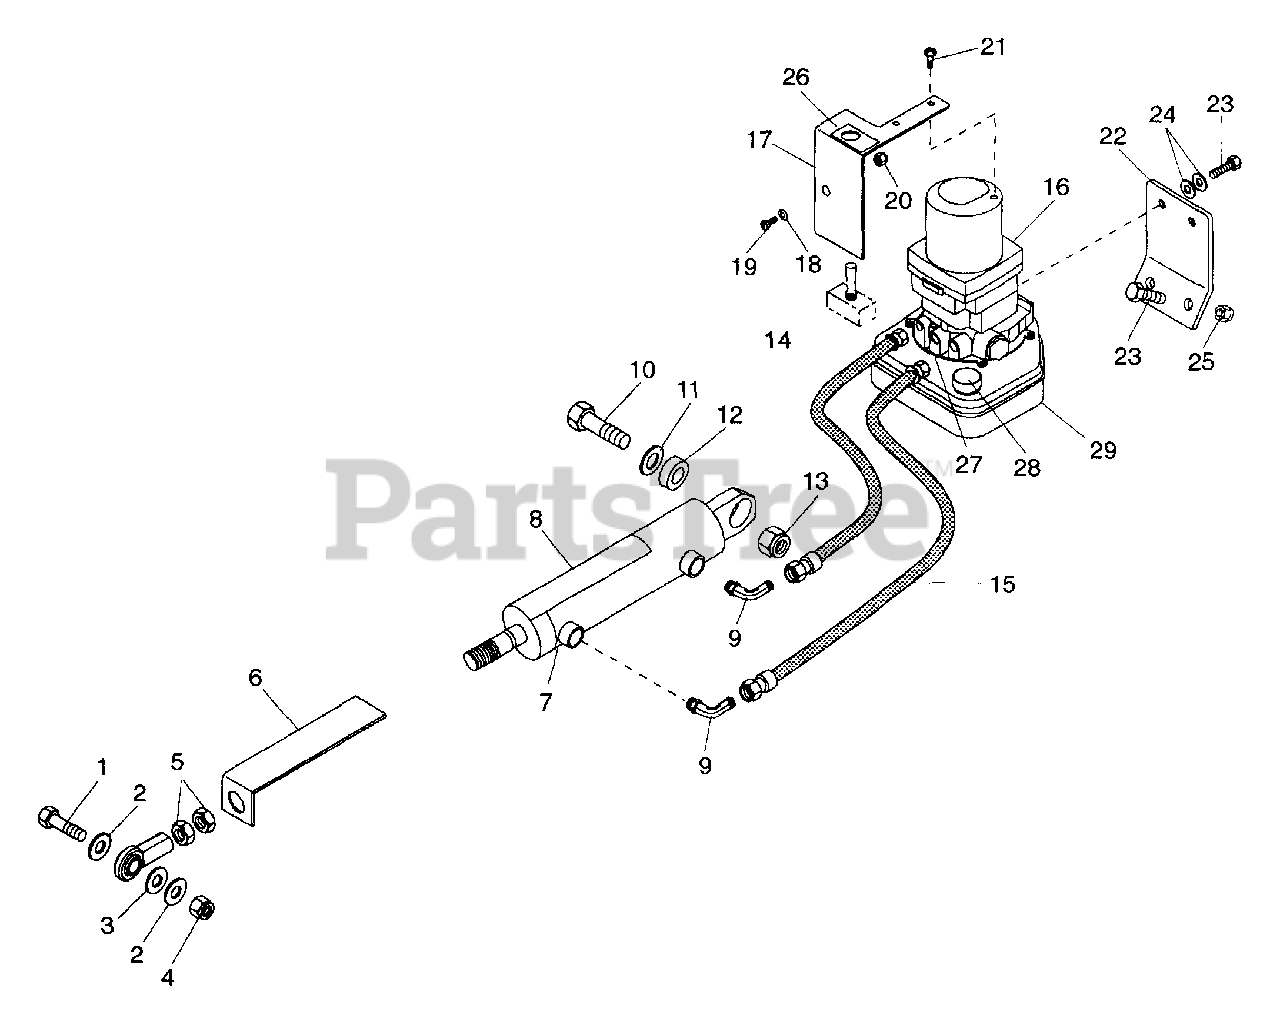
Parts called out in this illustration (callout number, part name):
1	Bolt-Hex .50-13 x 1.25 Grade 2
2	Washer-Flat-Steel .625 x 1.375 x .109
3	Rod End, 5/8" Female
4	Nut-Locking-Nylon .625-11 Grade 2
5	Nut-Jam .625-18
6	Strap-Height of Cut Indicator
7	Cylinder, Hydraulic Lift
8	Decal-Height of Cut
9	Adapter 2503-4-4
10	Bolt-Hex .50-13 x 2.25 Grade 5
11	Washer-Flat-Steel .531 x 1.250 x .100
12	Bushing, .516 x 1.000 x 1.050
13	Nut-Locking-Nylon .50-13 Grade 2
14	Assembly, Hose Pump to Cylinder
15	Assembly, Hose Pump to Cylinder
16	Pump, Electric Hydraulic
17	Switch Plate, Lift Pump
18	Washer-Flat-Steel .281 x .625 x .065
19	Screw-Machine .25-20
20	Nut-Locking-Nylon .250-20 Grade 2
21	Screw-Tapping 12-14 x .50
22	Lift Pump Mounting Bracket
23	Bolt-Hex .38-16 x .75 Grade 5
24	Washer-Flat-Steel .406 x .812 x .065
25	Nut-Locking-Nylon .375-16 Grade 2
26	Decal, Cutting Heat Treated Adjustment
27	Reservoir Seal, O-Ring
28	Reservoir Cap
29	Reservoir Tank
